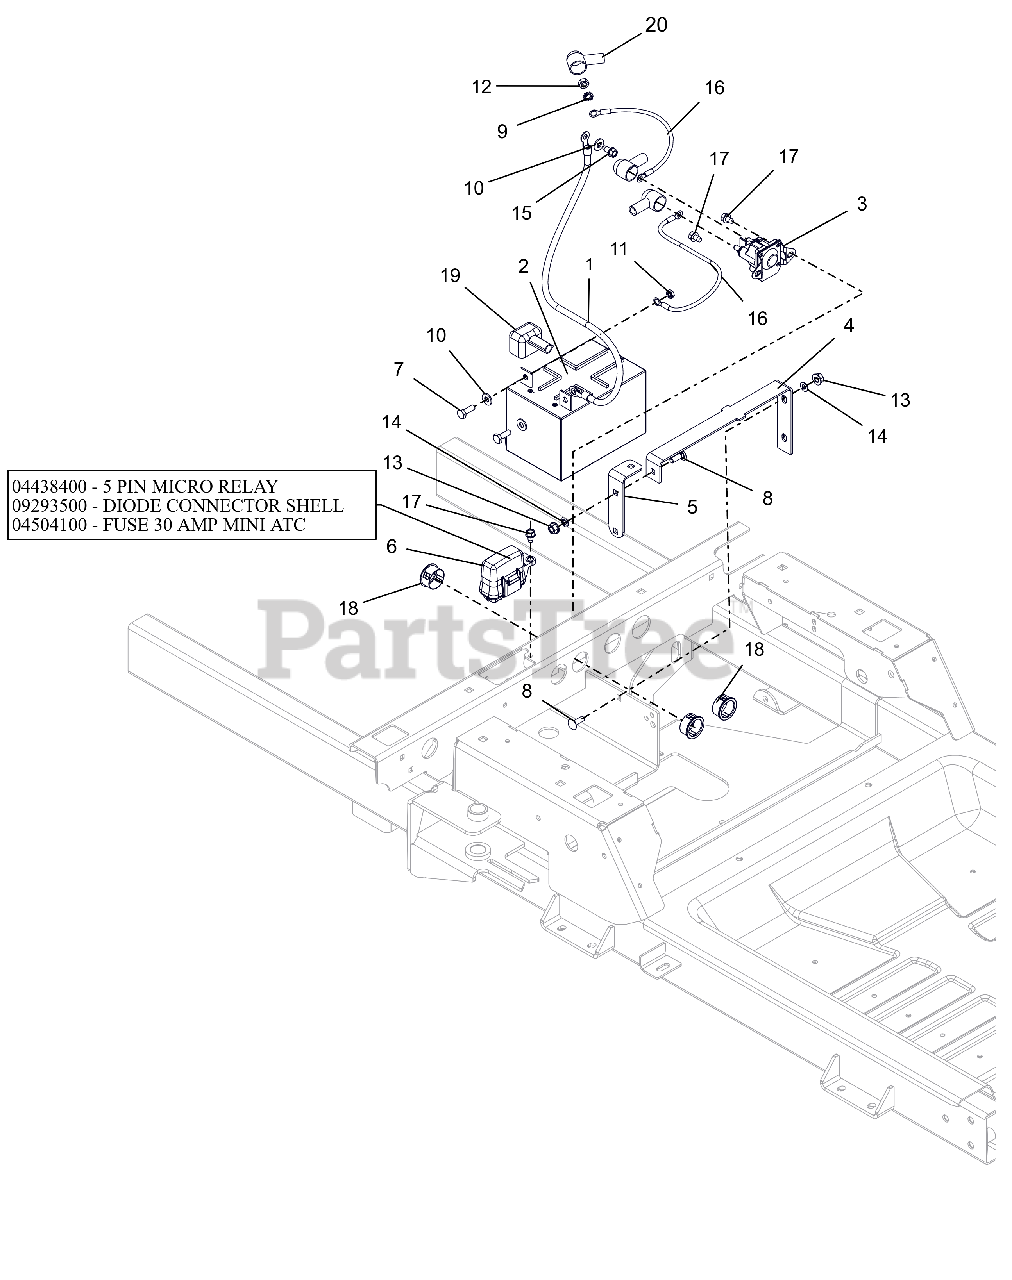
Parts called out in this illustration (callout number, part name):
1	CABLE-NEGATIVE BATTERY 24.00"
2	BATTERY, 12V 12A-190CCA
3	SOLENOID, STARTER (SEALED)
4	BRKT, BATTERY HOLD-DOWN
5	BRKT, BATTERY HOLD DOWN
6	HARNESS, WIRE-4POS KEY IKON/ZT
6	RELAY,MICRO5 TERML W/RESISTOR
6	DIODE, CONNECTOR SHELL
6	FUSE,30 AMP MINI-ATC
7	@BLT-HEX .25-20X.75 GR5 YWZC
8	@BLT-RDHDSQNK .25-20X.75 G5YZ
9	@WSHR-LK-EXT.262X.502X.026YWZC
10	@WSHR-FL-STL.281X.62X.065 YWZC
11	NUT, 10-24 KEPS
12	@NUT-HEX .25-20 YWZC
13	@NUT-LK-TOP-FLG .25-20 YWZC
14	NUT-PUSH .25X.50 O.D.
15	SCR-TAP .25-20X.50 HWH TR YWZ
16	CABLE,POS W/2 1/4 RING 15.0 LG
17	@SCR-TAP .25-20X.37 HWH YWZ TR
18	BSHG, PANEL SNAP .937X1.11X.56
19	INSULATOR
20	BOOT, EYELET TERMINAL
